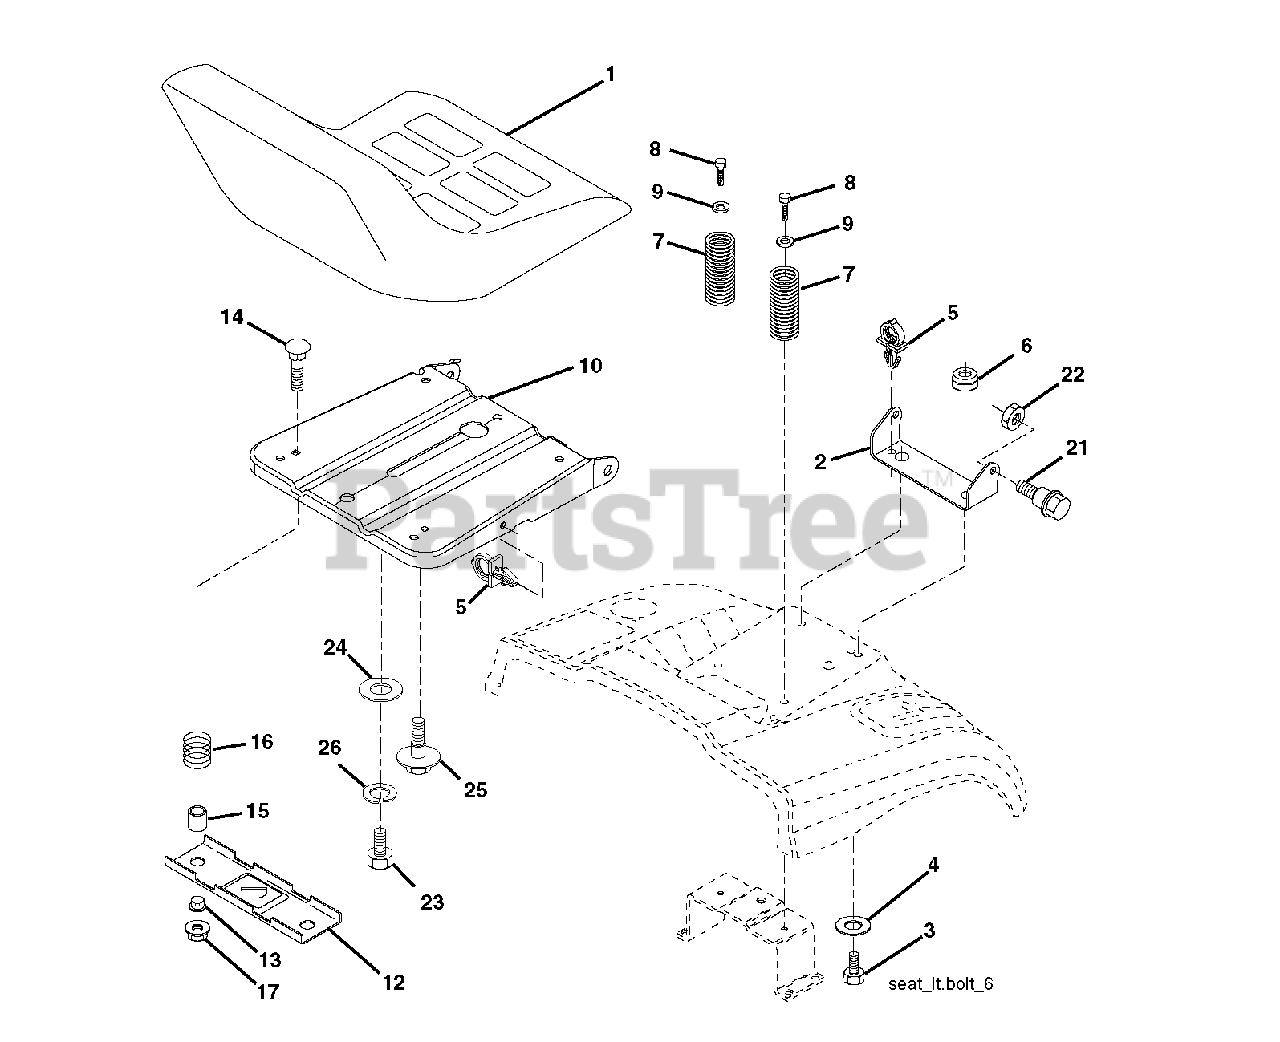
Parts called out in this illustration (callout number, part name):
1	SEAT.XG090.BLK.KB/BLT.NO-LOG
2	SEAT PIVOT BRKT
4	WASHER PM
5	PUSH CLIP
6	NUT
7	SPRING COMPRESSION
8	SCREW 3/8-16X1
9	WASHER
10	PAN.ASM.SEAT.1SLOT
12	BRKT.MNTNG.SWITCH.SEAT
14	BOLT.ROUND.HEAD.SQUARE.NECK
15	SPACER SPLIT 28X.96
17	NUT T
21	BOLT.SHOULDER.5/16-18
22	NUT.71038.31-18.HEX.NYLOCK
23	BOLT.HEX.BLACK
25	BOLT,SHOULD
26	LOCKWASHER
